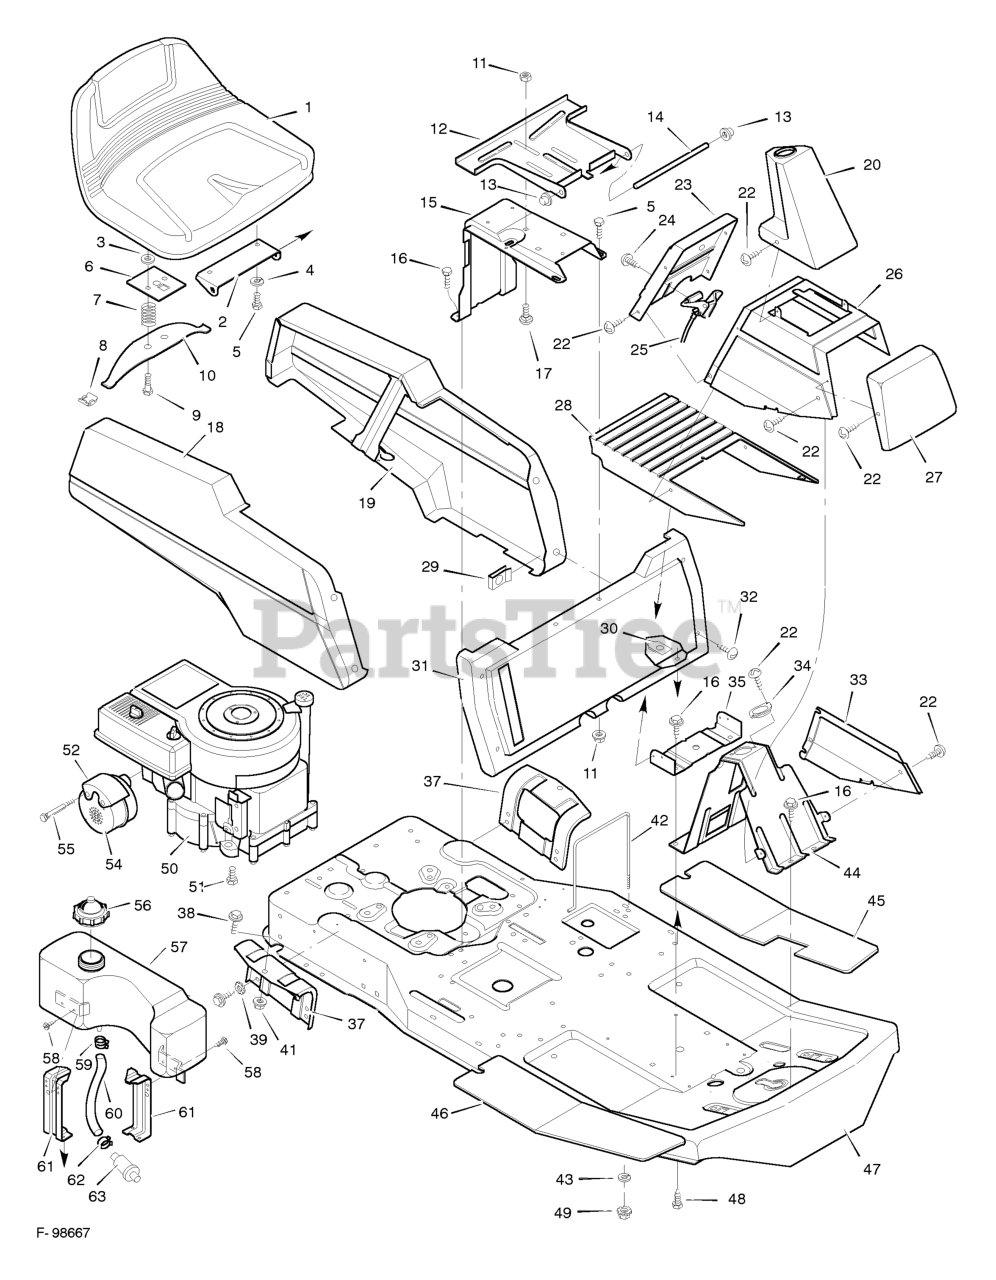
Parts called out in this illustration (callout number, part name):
2	Hinge, Seat
3	Retainer
4	Lockwasher
5	Bolt, Hex
6	Plate, Seat Switch
7	Spring, Compression
8	Glide, Seat Spring
9	Bolt, Shoulder
10	Spring, Seat
11	Locknut, Flange
12	Bracket, Seat Pivot
13	Cap, Push On
14	Rod, Seat Hinge
15	Support, Seat
17	Bolt, Carriage
18	Panel, Right Side
19	Panel, Left Side
20	Cover, Steering Column
22	Screw, Tapping
23	Panel, Control
25	Throttle Control
27	Cap, Front Console
28	Cover, Lower Console
29	Retainer
31	Panel, Front
32	Screw, Southco
33	Panel, Left Access
34	Bearing, Steering Post
35	Bracket, Cover Mounting
37	Support, Body
38	Bolt, Shoulder
39	Lockwasher
41	Locknut, Flange
42	Clamp Assembly, Battery
43	Washer
44	Support, Steering Column
45	Mat, Left
46	Mat, Right
49	Locknut
50	Engine, Briggs & Stratton *
51	Bolt, Engine Mount
52	Shield, Heat
54	Muffler
55	Bolt, Hex
56	Cap, Fuel
57	Tank, Fuel
58	Screw, Hex
59	Clamp, Hose
60	Line, Fuel
61	Bracket, Remote Tank
62	Clamp, Gas Line
63	Filter, Fuel
